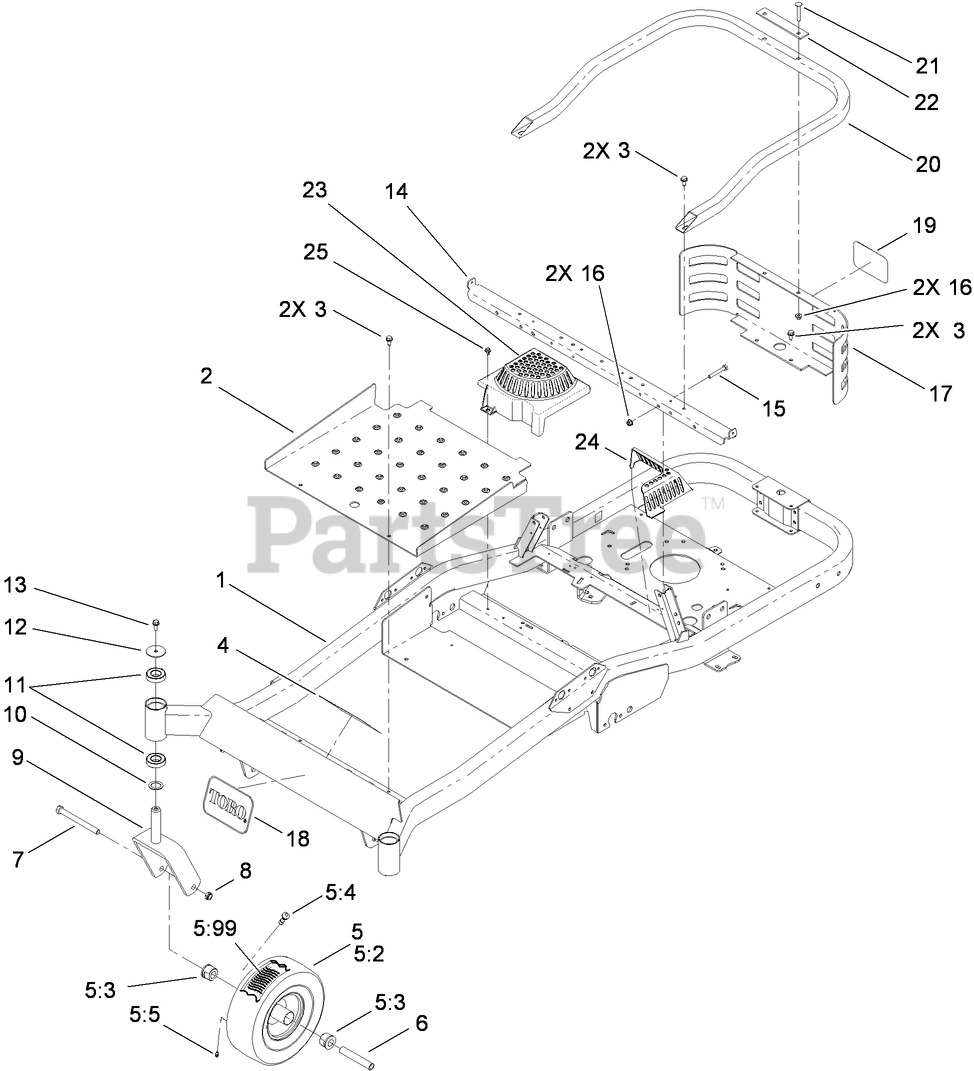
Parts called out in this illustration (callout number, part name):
3	SCREW-HWHTF
4	DECAL-SAFETY
5	TIRE AND WHEEL ASM (KENDA)
5:2	TIRE-SMOOTH
5:3	BUSHING-FLANGE
5:5	FITTING-GREASE
5:99	TUBE-INNER
6	BUSHING-SPANNER
7	SCREW-HH
8	NUT-HEX
9	CASTER FORK ASM
10	WASHER-THRUST
11	BEARING-BALL
12	WASHER
13	SCREW-HHF
14	SUPPORT-SEAT
15	SCREW-HH
16	NUT-HF, NI
18	DECAL
20	GUARD-REAR, TUBE
21	BOLT-CARR
22	PLATE-SPACER
23	COVER-FAN, RH
24	COVER-FAN, LH
25	SCREW-HHFTF
